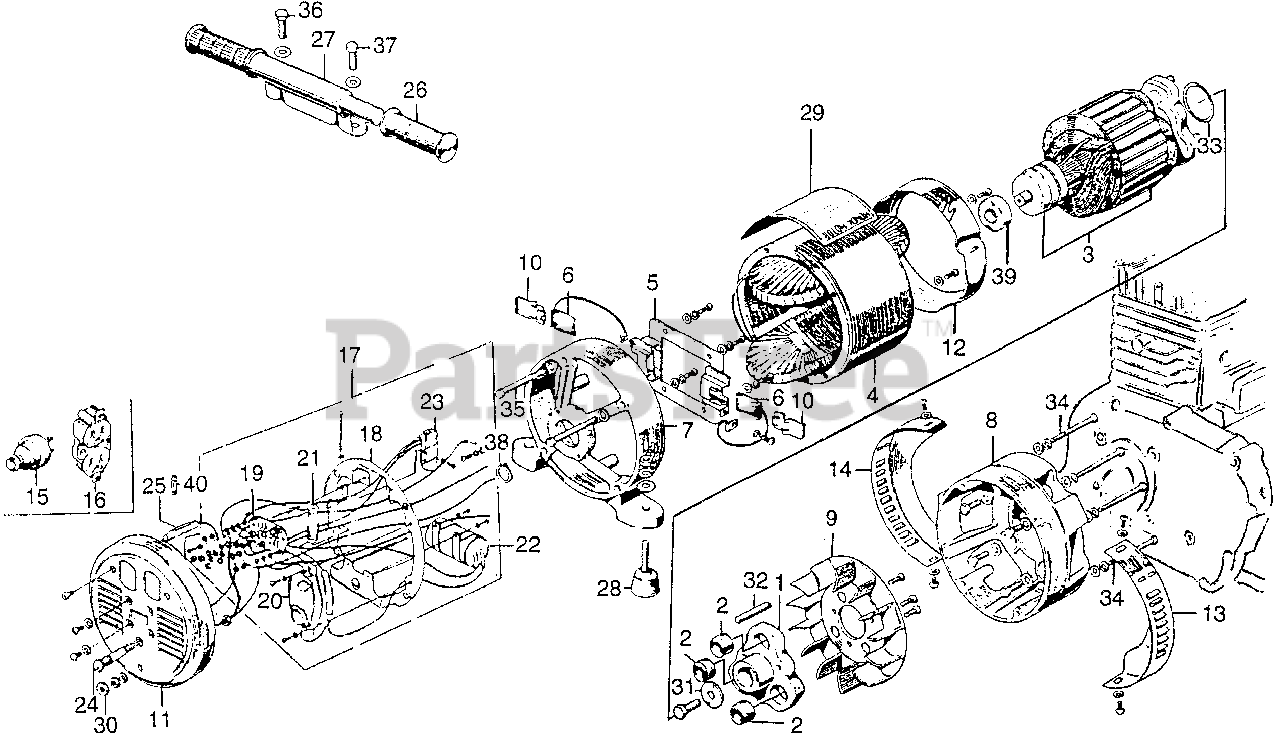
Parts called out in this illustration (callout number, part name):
1	FLANGE, COUPLING A
2	RUBBER, COUPLING
3	ROTOR ASSY.
4	STATOR ASSY.
5	RIG PLATE ASSY.
6	BRUSH (NOT AVAILABLE)
7	COVER, END
8	COVER, FR.
9	FAN, GENERATOR
10	SPRING, BRUSH (NOT AVAILABLE)
11	COVER, CLEANER
12	PLATE, GUIDE (NOT AVAILABLE)
13	PROTECTOR A, GENERATOR FAN *R8* (BRIGHT RED)
14	PROTECTOR B, GENERATOR FAN *R8* (BRIGHT RED)
15	PLUG ASSY., RECEPTACLE
16	RECEPTACLE (15A-125V)
17	TRANSISTOR REGULATOR ASSY.
19	DIODE ASSY.
20	CONTROL ASSY.
21	RESISTOR ASSY.
22	CONDENSER ASSY. A (NOT AVAILABLE)
23	CONDENSER ASSY. B
24	LAMP, PILOT
25	HOLDER, FUSE
26	GRIP B, L. HANDLEBAR
27	HANDLE, CARRYING
28	RUBBER, GENERATOR (LOWER) (NOT AVAILABLE)
29	PLATE, CAUTION (ATTACHED TO STATOR)
30	NUT, SPECIAL (6MM)
31	WASHER (8MM)
32	KEY (7X7X33)
33	O-RING (35.5X3) (NOK)
34	BOLT, HEX. (6X55)
35	BOLT, HEX. (6X55)
36	BOLT, HEX. (8X14)
37	BOLT, HEX. (8X22)
38	CIRCLIP (OUTER) (17MM)
39	BEARING, RADIAL BALL (6203UU)
40	FUSE A (15A)
